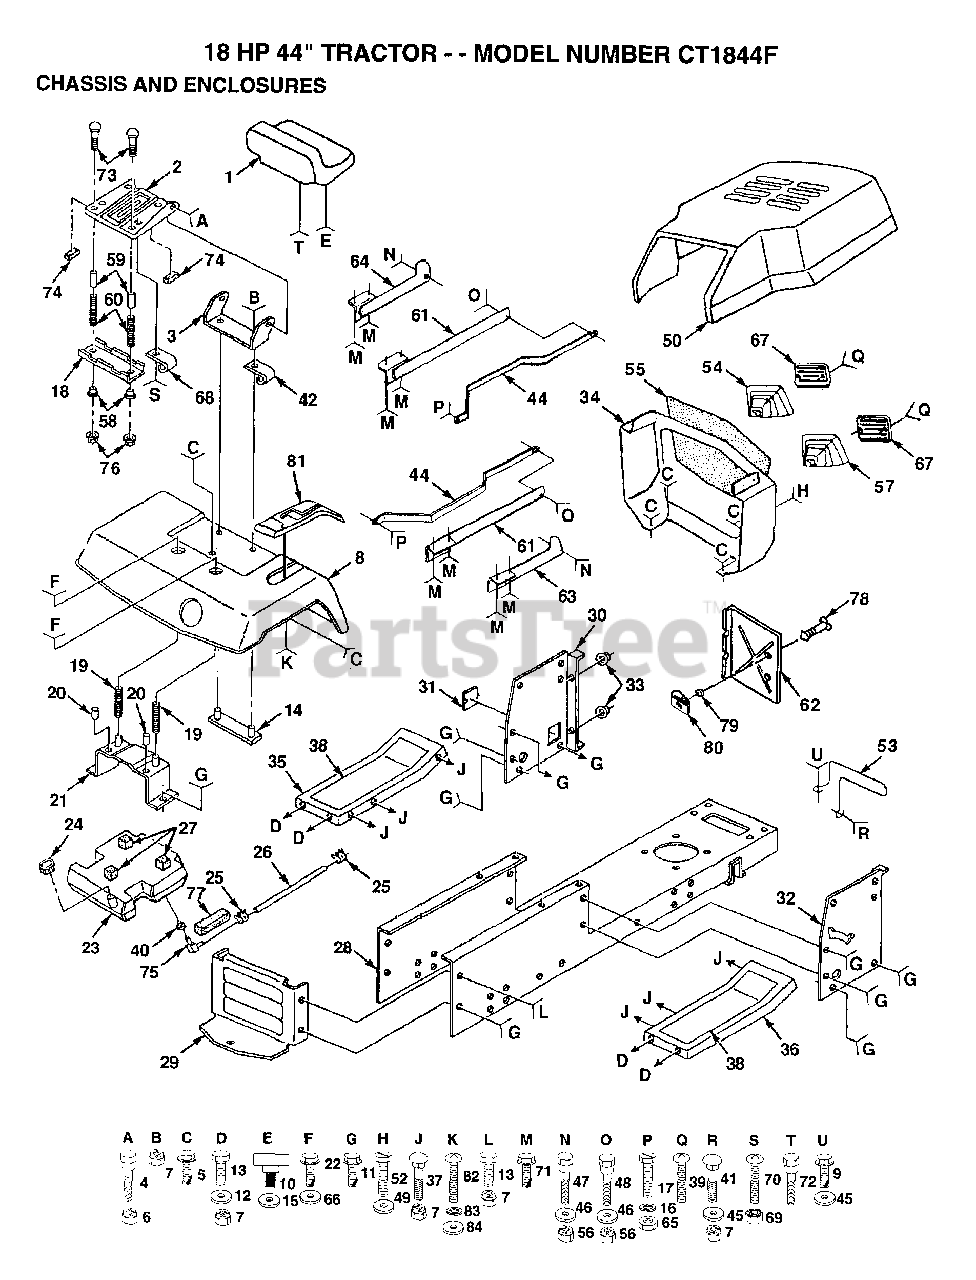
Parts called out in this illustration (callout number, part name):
5	SCREW LT
8	FENDER
9	SCREW GTV
10	"KNOB 1/2"" YT"
11	SCREW
12	WASHER
15	WASHER
16	LOCKWASHER
17	BOLT LT
18	BRKT SWITCH
19	SPRING COMPRESSIO
20	NUT-PUSH YT
21	BRKT.ASM.FENDER
22	SCREW LT
25	HOSE CLAMP
27	PAD-SPACER LT
28	CHASSIS
29	DRAW BAR
30	PANEL.DASH.LH
31	COVER ACCESS
32	PANEL.DASH.RH
37	BOLT
38	FOOTREST PAD
40	BUSHING OUTLET T
41	BOLT D
42	CLIP T
45	WASHER HYT
47	BOLT T
48	"BOLT,SHOULDER"
52	SCREW
53	MUFFLER GUARD
55	SCREEN GRILL GTV
58	BUSHING
59	SPACER SPLIT
60	SPRING COMPRESSED
61	STRAP ASSY-REAR T
62	HEAT SHIELD
63	STRAP ASSY T
64	STRAP ASSY T
66	WASHER
69	"NUT,KEPS"
72	"BOLT,SHOULDER"
74	STRIP FORM
75	STEM.TANK.FUEL
77	PAD IDLER TI
78	STUD.1/4.TURN
79	RETAINER LT
80	RECEPTACLE LT
81	CONSOLE SHIFTER
82	SCREW
83	"WASHER,LOCK"
84	WASHER
